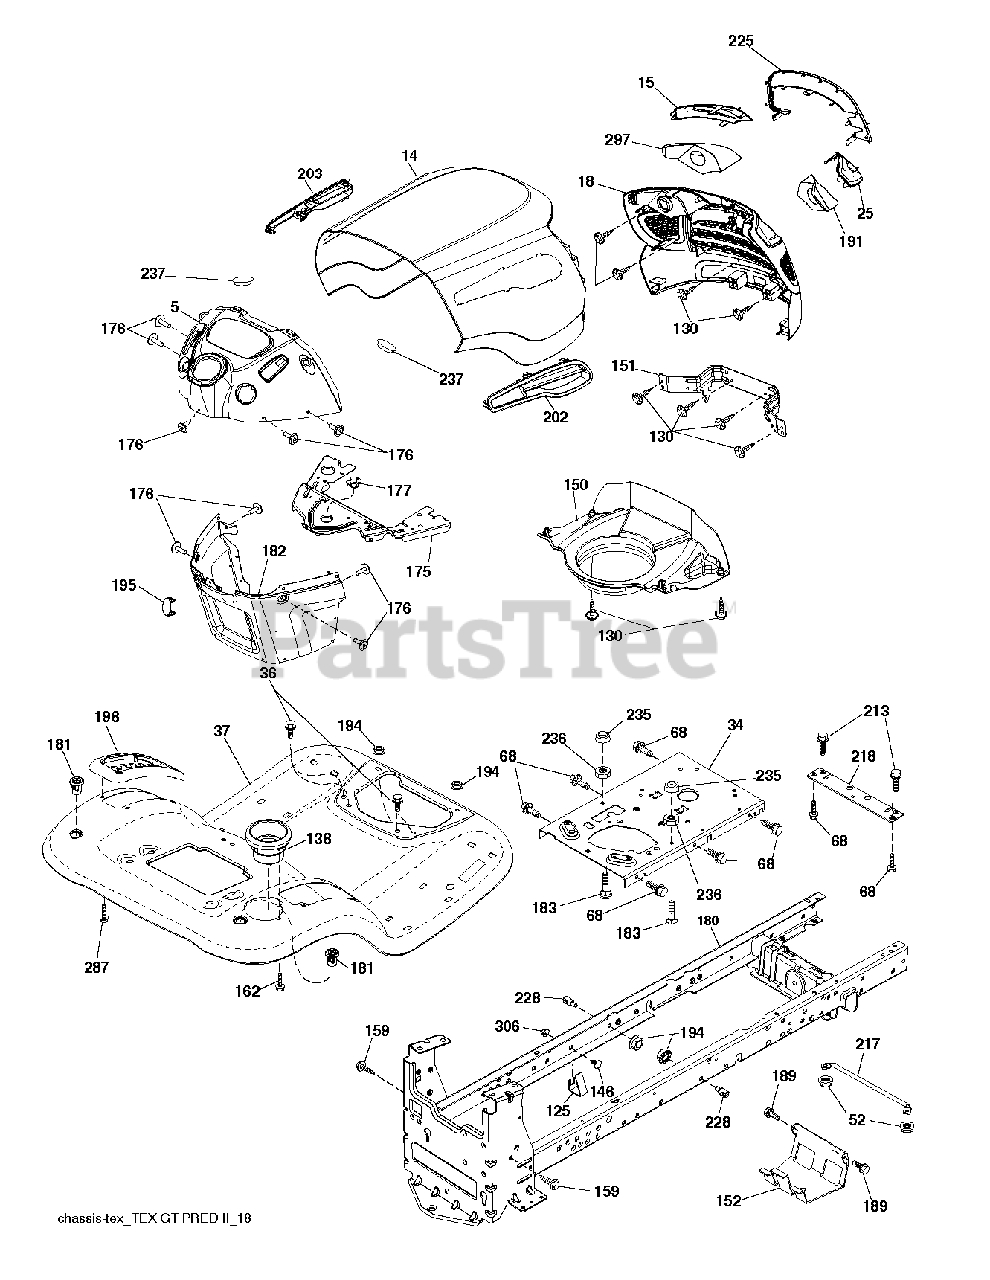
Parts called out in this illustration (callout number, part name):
5	DASH.UPPER.PREDATOR.YT/GT
14	HOOD.PNT.PREDATOR.YT/GT.BLACK
15	LENS.MCCULLOCH.GT.LH
18	GRILLE.PREDGT2.GEN
25	Lens, RH Mcculloch GT
34	PLATE.ENGINE.WELDED.CHASSIS
36	SCREW 5/16"
37	FENDER.TLT.W/CPH.428
52	LOCKNUT
68	SCREW LT
125	CLIP.FUEL.LINE
130	SCREW.#10 X 0.750.BOS (2 2)
138	CUPHOLDER.TL.TEX.BLACK
146	BOLT.RDHD.SHT.SQNK.3/8-16X5/8
150	PREDATOR.YT.GT.HOOD.AIR DUCT
151	BRACKET.PIVOT.PREDATOR
152	SHIELD.BROWNING.W/TEX
159	SCREW, 3/8-16X3/4
162	SCREW.HI-LO.CONSOLE
175	PLATE.CROSSMEMBER.HUSQ
176	SCREW.#10-24X5/8.RN.QU
177	BUSHING STEERING
180	CHASSIS
181	FEND/FTRST.PCH.CPH.NFW
182	DASH LOWER.HUSQ.PRED NO CRUISE
183	BOLT.5/16-18X1-1/4 FULL THD
189	SCREW
191	REFLECTOR.MCCULLOCH.GT.RH
194	NUT LOCK HEX FLANGE 5/16-18
195	PLUG.HOLE.DASH.
202	VENT.SIDE.HOOD.RH.PREDATOR.BLK
203	VENT.SIDE.HOOD.LH.PREDATOR.BLK
213	BOLT
217	ROD.PIVOT.HOOD
218	X-PIECE.HOOD.STOP.NON/
228	STUD.FASTNER.W/ANTI-ROTATE
235	SPACER FENDER
236	NUT.CENTERLOCK.5/16-
237	PLUG.MOUNT.CARGO.BLK
287	SCREW 1/4X20
297	REFLECTOR.MCCULLOCH.GT.LH
306	NUT LOCK FLG 3/8-16 UNC
